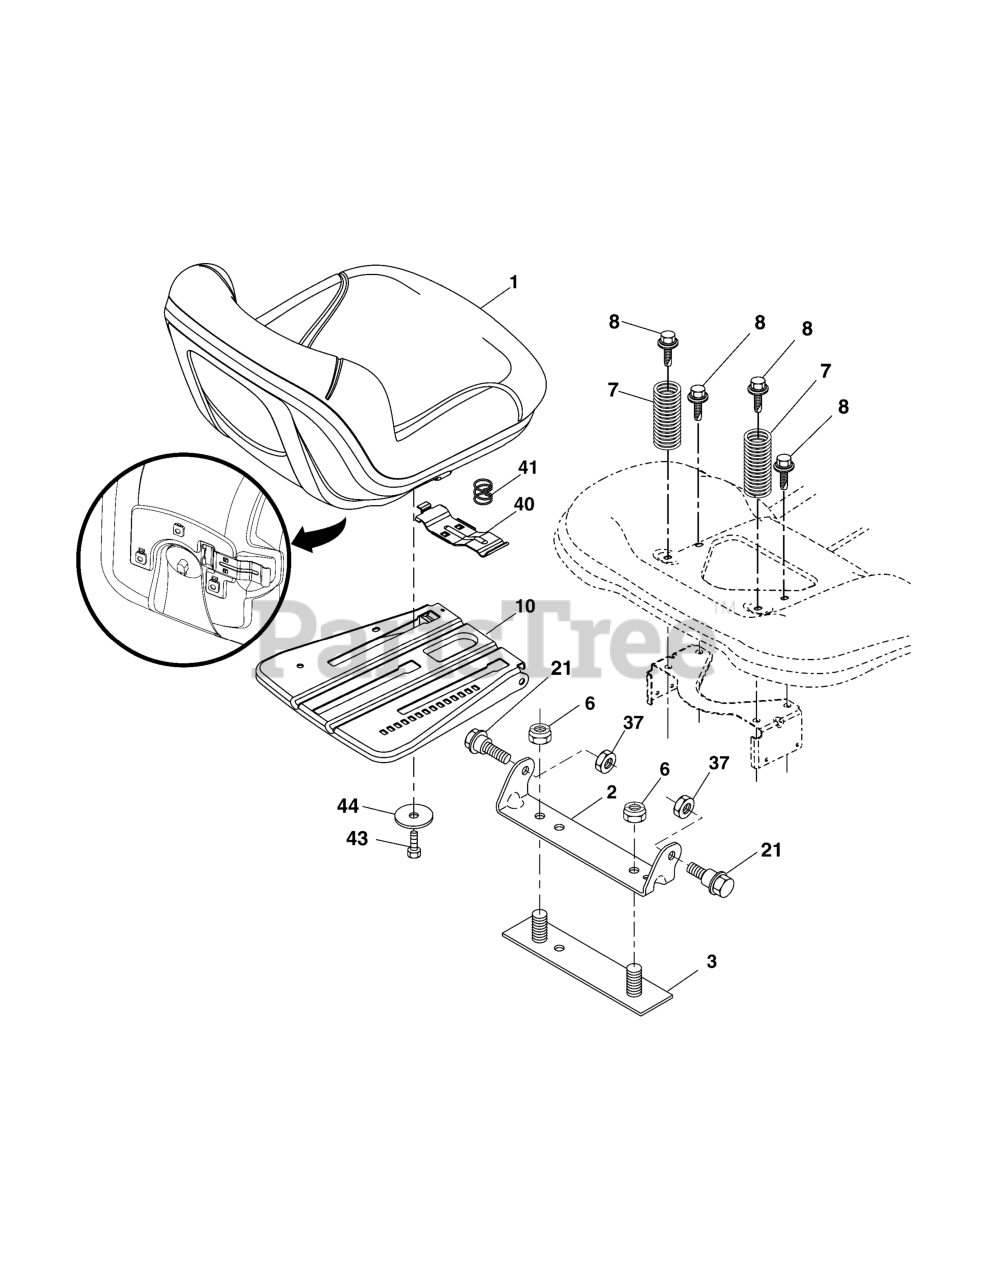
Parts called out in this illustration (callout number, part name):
2	Bracket Pivot Fender
3	Strap, Asm Fender
6	Nut, Lock w/Ins. 3/8-16 unc
7	Spring, Seat Cprsn
8	Bolt 5/16-18 unc x 3/4 w/Sems
10	Pan, Seat
21	Bolt, Shoulder 5/16-18
37	Nut, Lock 5/16-18 unc
40	Handle Slide Seat
41	Spring Latch Seat
43	Bolt 3/8-16 x 3/4
44	Washer 13/32 x 2-3/8 x 12 Ga.
